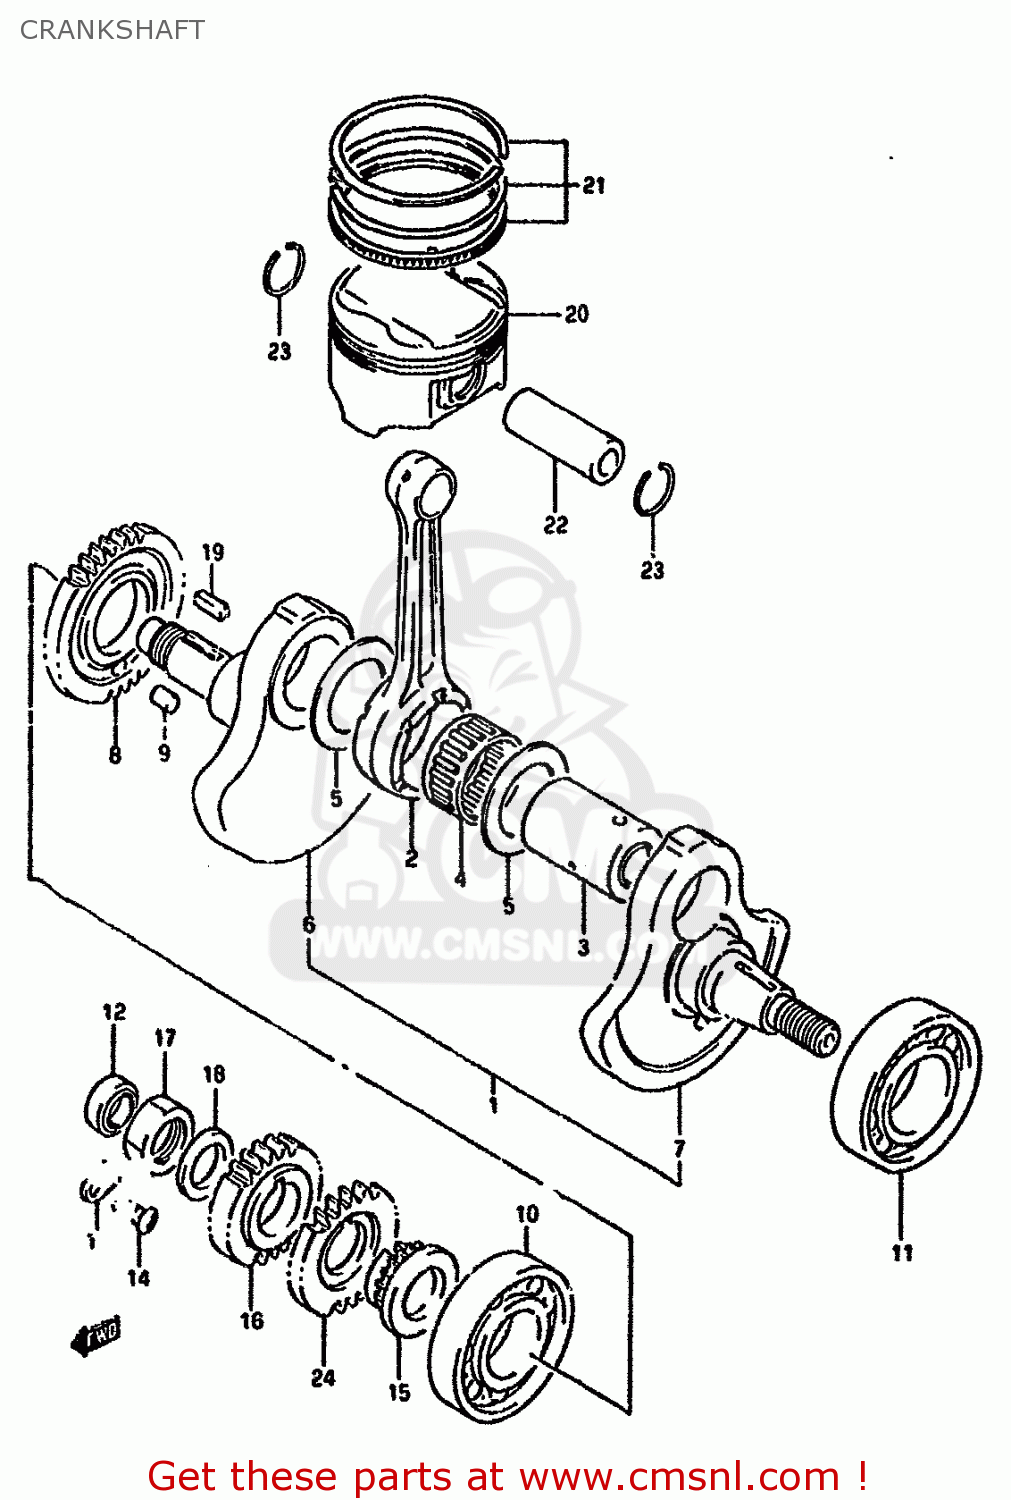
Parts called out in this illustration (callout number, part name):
1	CRANKSHAFT ASSY
2	ROD,CONNECTING
3	PIN COMP,CRANK
4	BEARING(34X43X22)
5	WASHER(34X52X1)
6	CRANKSHAFT
7	CRANKSHAFT,L
8	GEAR,CRANK BAL DRIVE(NT:37)
9	PIN
10	BEARING(30X72X19)
11	BEARING(35X72X17)
12	SEAL,OIL(14X24X6)
13	RETAINER,BEARING
14	SCREW
15	SPROCKET,CAM CHAIN DRIVE
16	GEAR,PRIMARY DRIVE
17	NUT
18	WASHER
19	KEY
20	PISTON
21	RING SET,PISTON
22	PIN,PISTON
23	CIRCLIP,PISTON PIN
24	GEAR,OIL PUMP DRIVE
